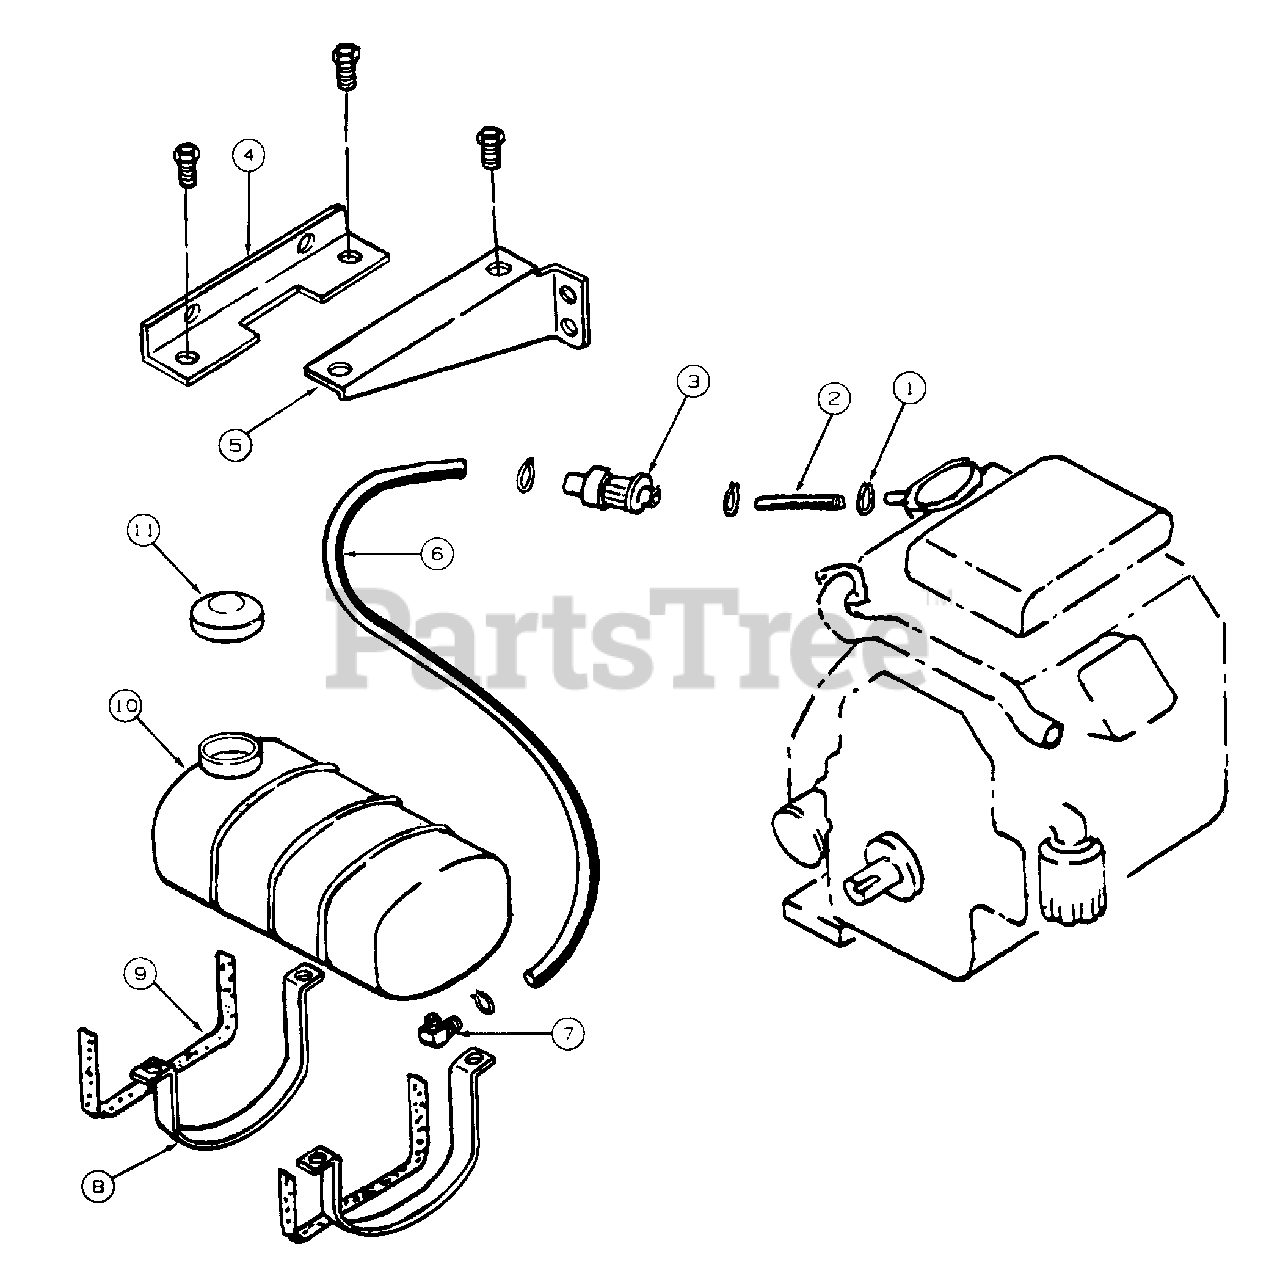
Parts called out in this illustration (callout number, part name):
1	Clamp, Hose
2	Line, Fuel 6 in. Lg
3	Filter, Fuel
4	Bracket, Gas Tank Front Mtg.
5	Bracket, Gas Tank Rear Mtg.
6	Line, Fuel 27 in. Lg
7	Fitting, 1/4 to 1/8 Pipe 90 Degree
8	Strap, Tank Mtg
9	Foam Rubber, 1/4 X 1/2
10	Gas Tank (3.75 gal w/cap)
11	Cap, Gas Tank
